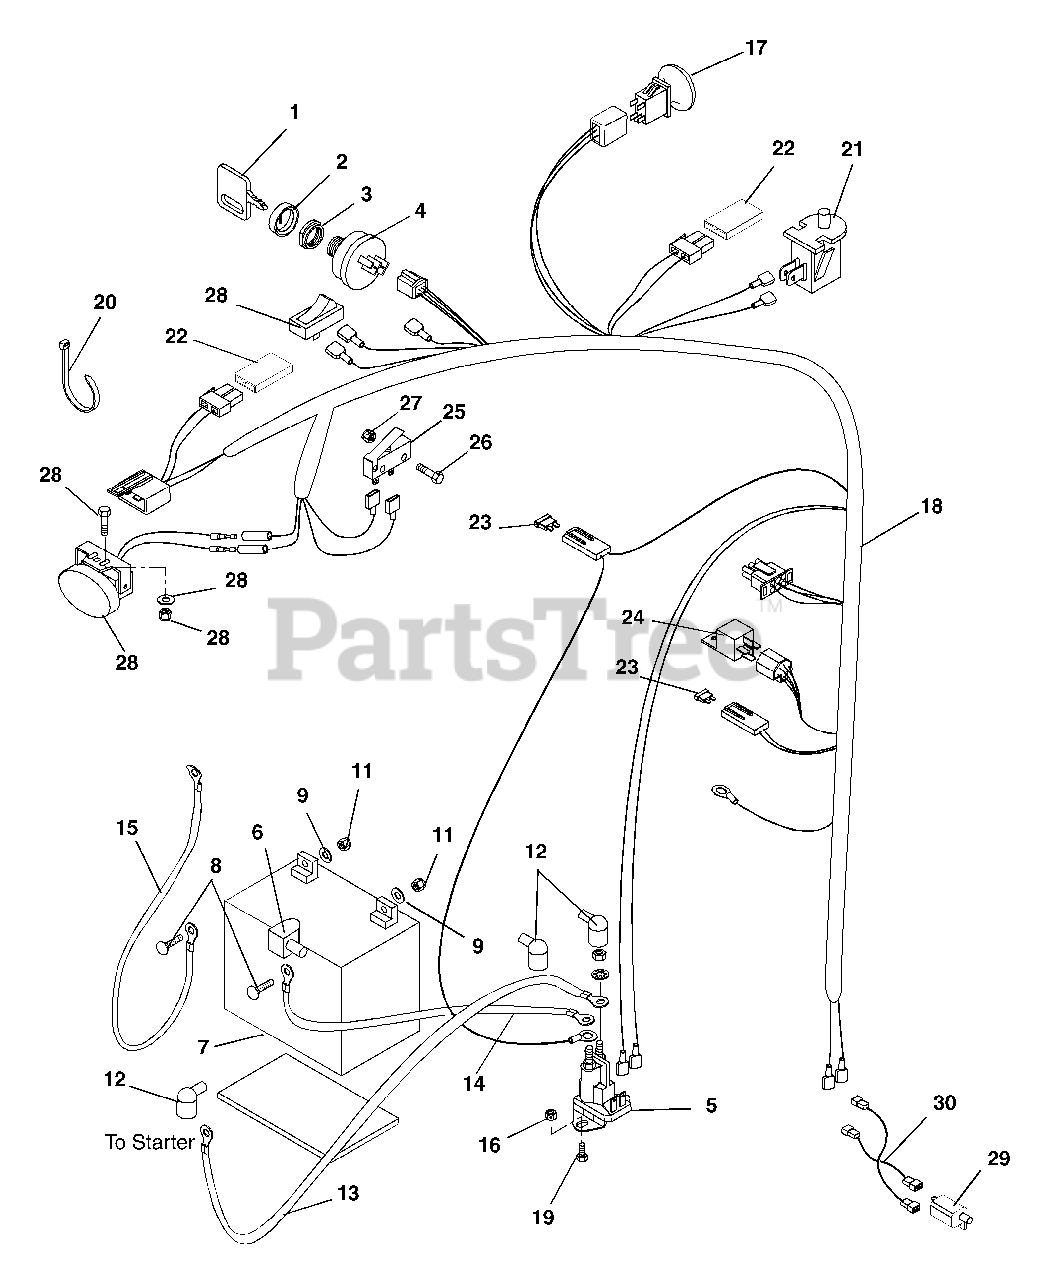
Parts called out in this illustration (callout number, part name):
1	KEY -W/CAP
2	CAP - IGNITION SWITCH
3	NUT- PANEL .562-24 GRECO
4	SWITCH KEY 5Y463A ALT GRDNG
5	SOLENOID
6	INSULATOR
8	@BLT-HEX .25-20X.75 GR5 YWZC
9	@WSHR-FL-STL.281X.62X.065 YWZC
10	@WSHR-LK .25X.062 REG YWZC
11	@NUT-HEX .25-20 YWZC
12	BOOT, EYELET TERMINAL
13	STARTER CABLE 13"
14	STARTER CABLE 16"
15	CBL,NEGATIVE BATTERY 20.00
16	@NUT-SPNLK-FLG .312-18 YWZC
17	SWITCH, CLUTCH
18	WIRE HARNESS - RER
19	@SCR-TAP 10-24X.375 HWH YZ TR
20	CABLE TIE LG 5-1/2
21	SWITCH- SNAP MTG N.O.
22	DIODE, CONNECTOR SHELL
23	FUSE-25 AMP ATC TYPE
24	RELAY
25	SWITCH, RER PARK BRAKE
26	SCREW, MACHINE 2-56 X 3/4
27	NUT, NYLK 2-56 PL
28	KIT-LIGHT RER/SPORT
29	SWITCH- SINGLE POLE N.O.
30	JUMPER, HARNESS
